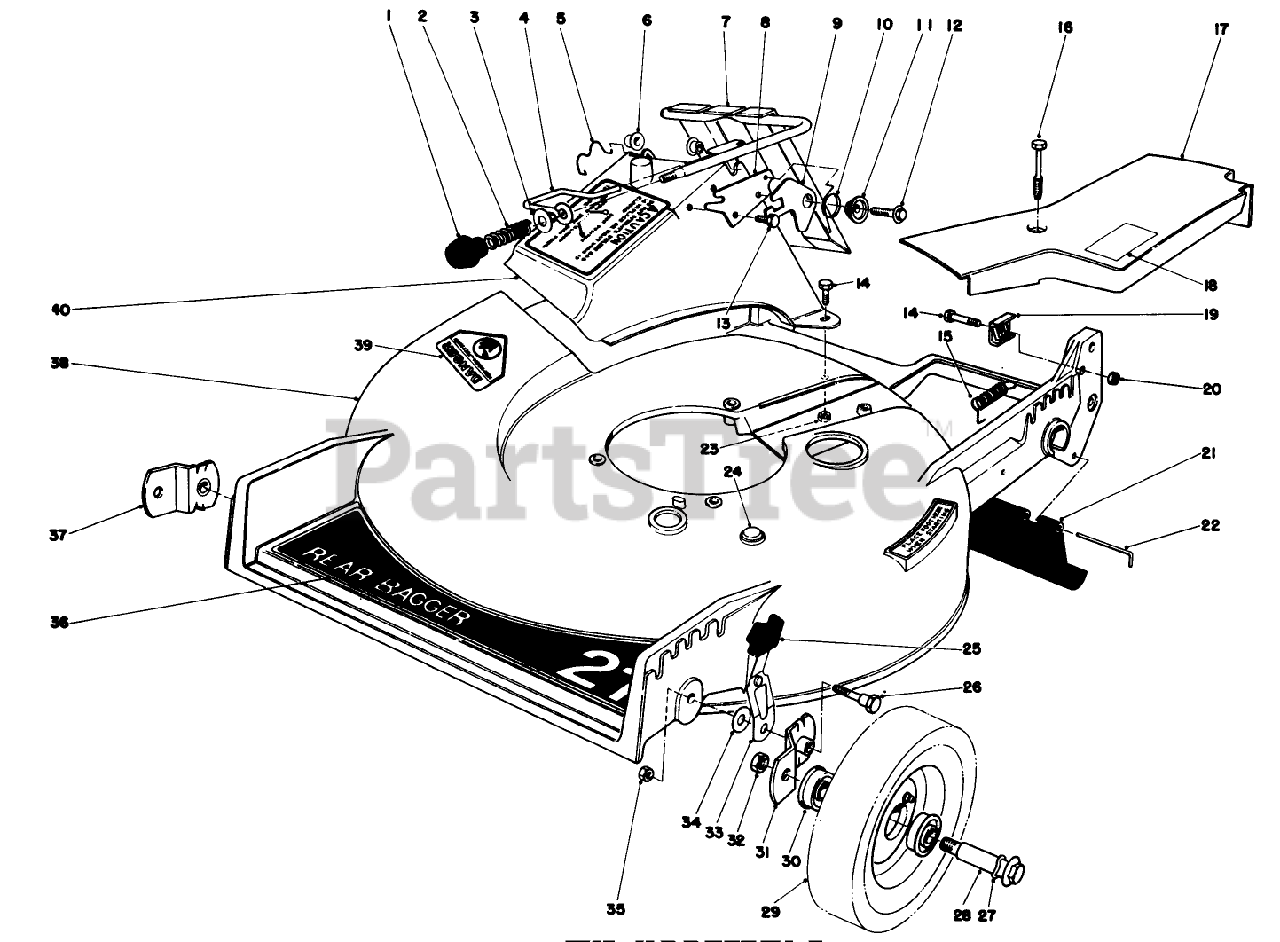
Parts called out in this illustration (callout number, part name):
2	Spring Compression
3	WASHER-FLAT
4	DOOR LATCH
5	DOOR RETAINER
6	BUSHING-NYLON
8	DOOR LATCH PLATE
9	Latch-Door
10	Spring-Torsion
13	SCREW-HWH
14	SCREW-HH
15	IDLER SPRING
16	SCREW-HWH
19	CLAMP-CABLE
20	NUT-JAM
21	SHIELD - TRAILING
23	NUT-LOCK, NI
25	KNOB-ARM
26	PIVOT SCREW
27	SPRING WASHER
30	BEARING-BALL
31	PIVOT ARM ASM A
33	Spring Arm
34	Washer
37	PIVOT ARM ASM
39	DECAL-DANGER
40	DISCHARGE CHUTE *B
